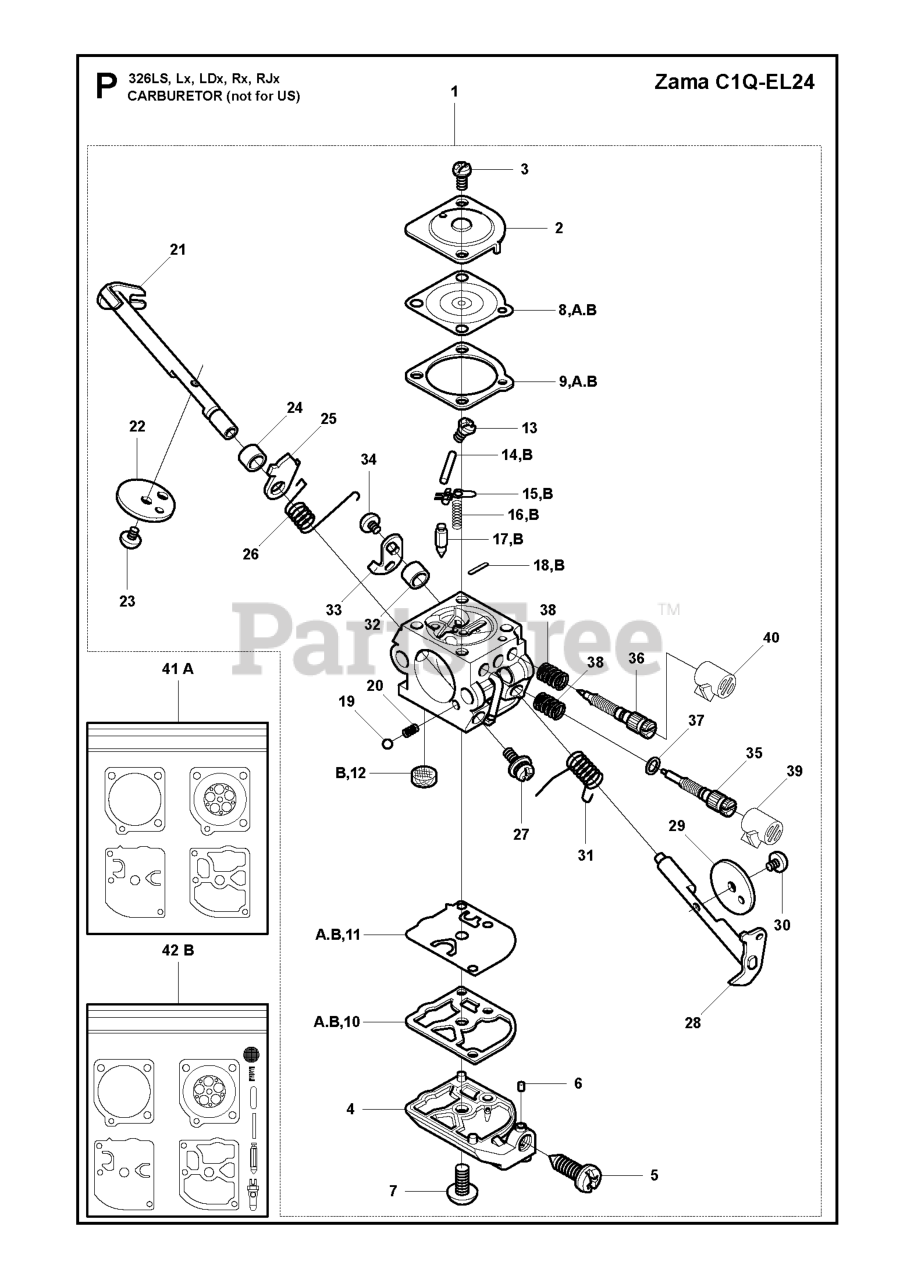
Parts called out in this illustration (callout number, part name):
1	CARBURETOR
11	PUMP DIAPHRAGM
14	PIN RETAINING SCREW
16	SPRING
17	INLET NEEDLE
21	CHOKE SHAFT
29	THROTTLE FLAP
31	SPRING THROTTLE
35	NEEDLE HIGH SPEED
36	LOW SPEED NEEDLE
38	SPRING
41	GASKET KIT (ZAMA GND39)
42	CARBURETOR KIT (ZAMA RB69)
